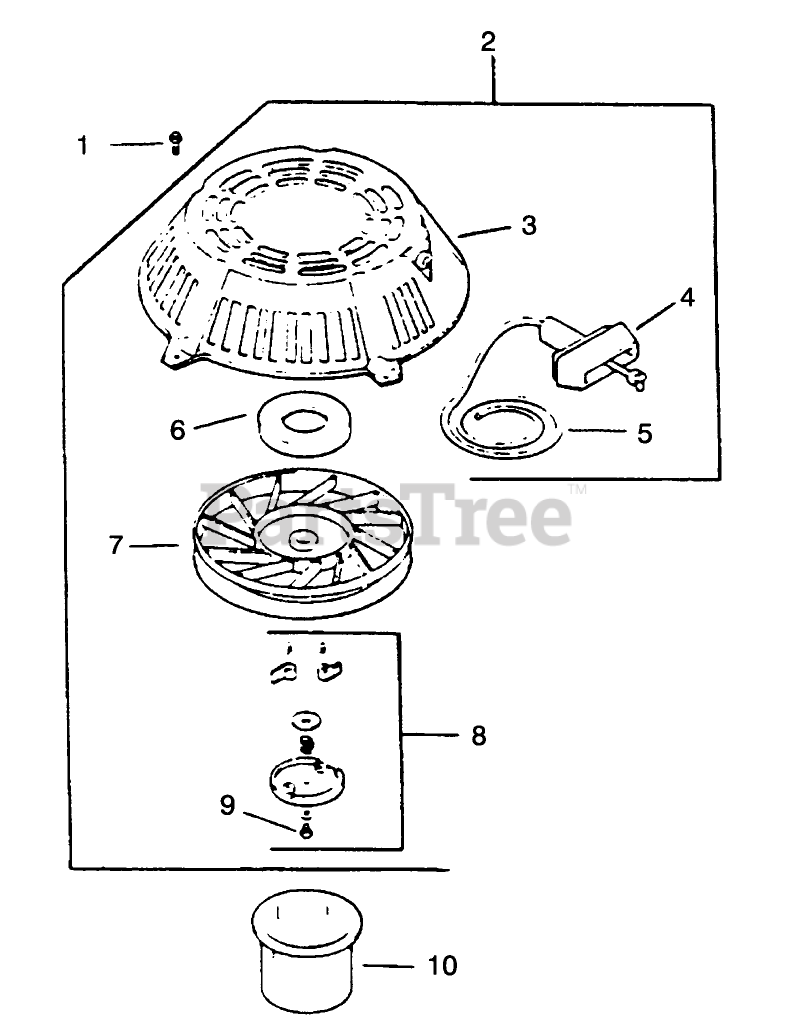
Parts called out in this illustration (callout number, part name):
2	Starter (Incl.Ref.#3-9)
3	Housing-Starter
4	Handle
5	Rope
6	Spring Keeper
7	Pullet
8	Kit-Dog Replacement
10	Cup-Drive
